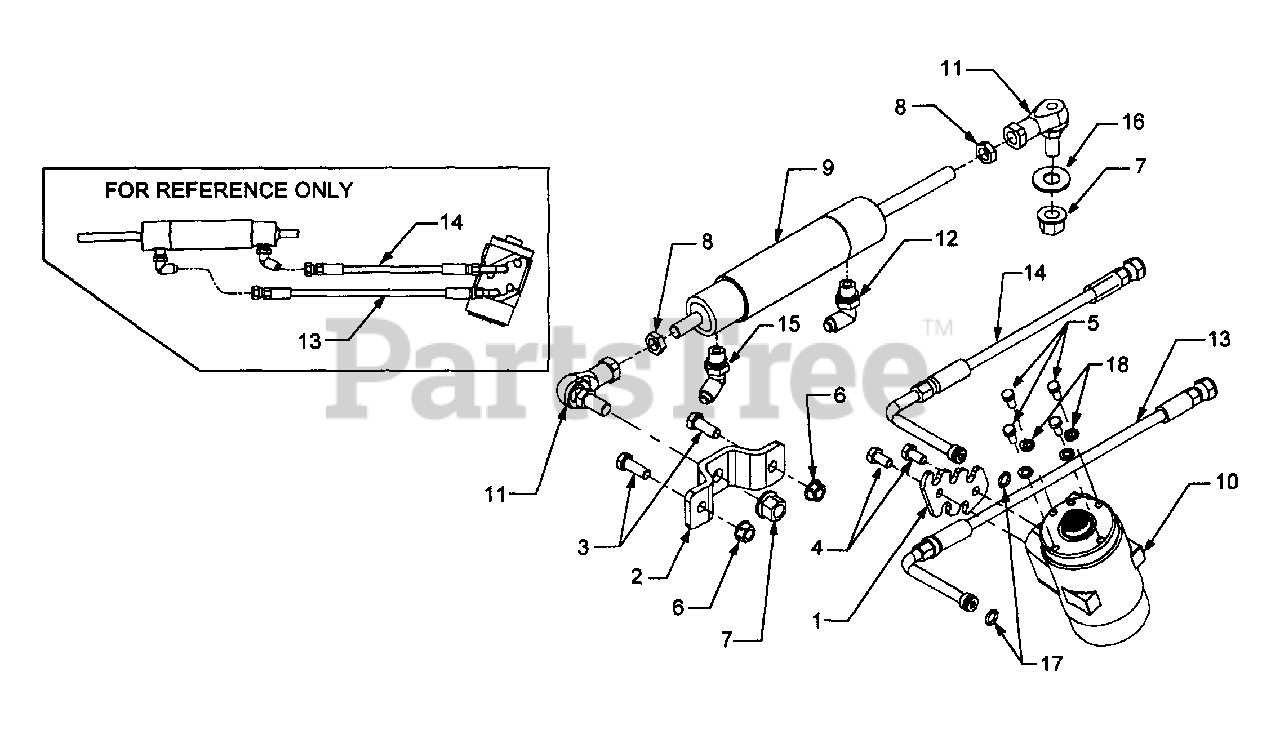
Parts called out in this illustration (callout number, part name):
1	Plate, Steering Pump Port
2	Bracket, Cylinder Mounting
3	Screw, Hex Cap 3/8-16 x 1.0 GR5
4	Screw, Hex Cap M8-1.25 x 16MM GR5
5	Screw, Hex Cap, M6 x 14MM
6	Nut, Hex Flange Lock, 3/8-16
7	Nut, Hex Flange Lock, M12 x 1.75
8	Nut, Hex, M12 x 1.75 RH
9	Cylinder, Steering
10	Pump, Hydraulic Steering
11	Ball Joint, 12MM x 1.75 RH
12	Fitting, 90 Degree Elbow
13	Hose, Front Steering
14	Hose, Rear Steering
15	Fitting, 45 Degree
16	Washer, Flat, .51 x 1.12 x .060
17	O-Ring, .426 x .566 x .070
18	Washer, Lock, 1/4"
